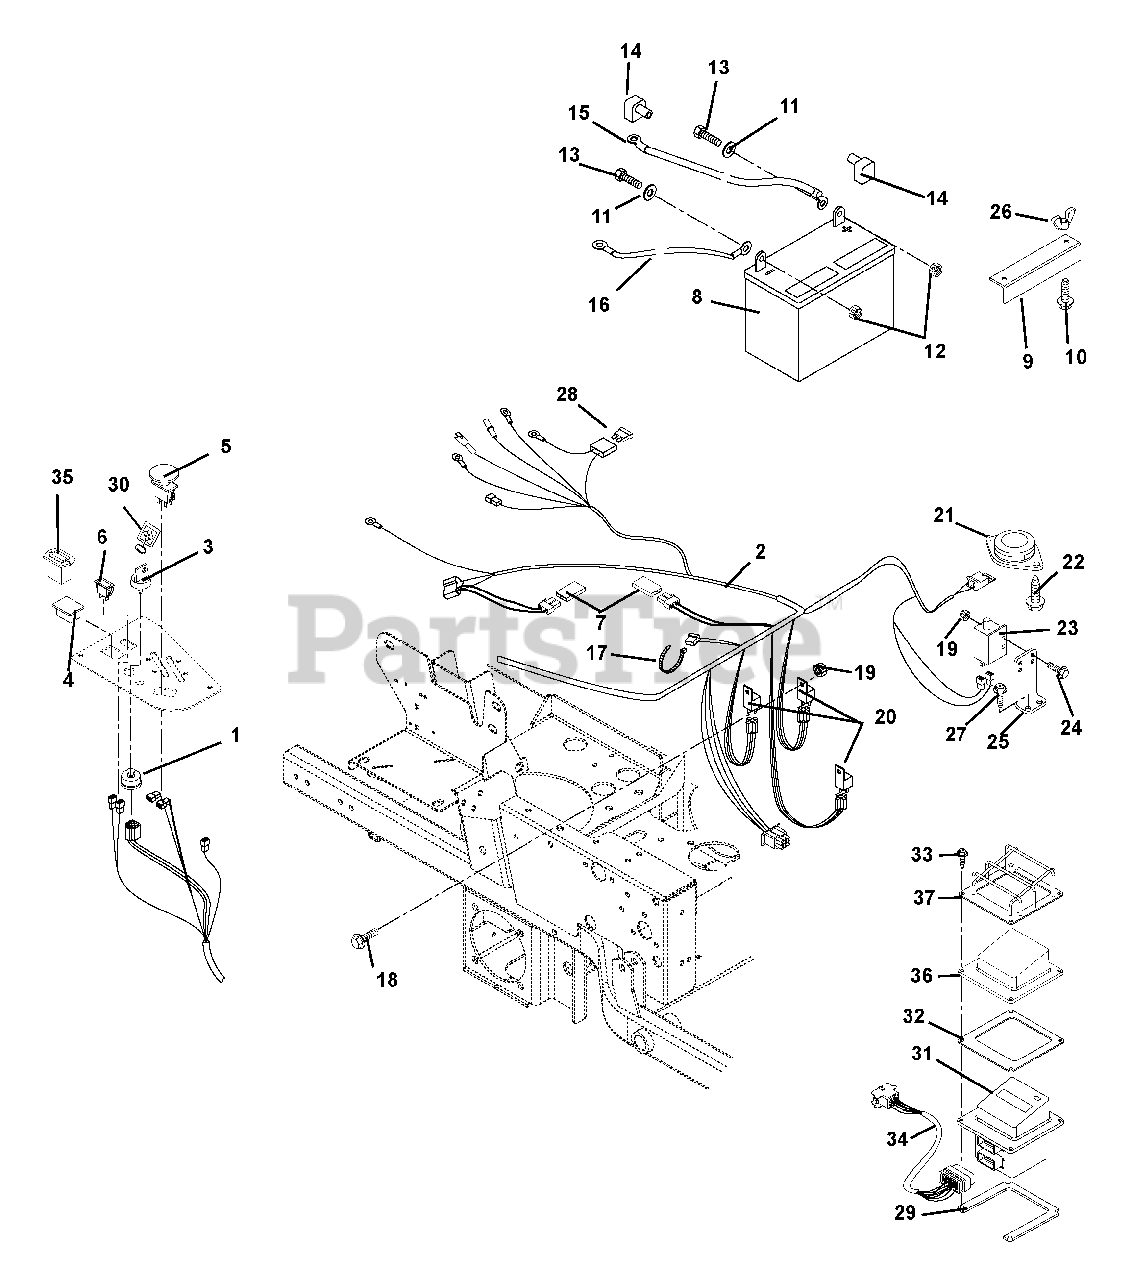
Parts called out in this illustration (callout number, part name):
1	Key Switch
2	Harness, IZ-6 Pin (EYE-Q)
3	Key with Shield
4	Plug (992077, 078, 079, 080, 081, 082, 310, 311)
5	Switch, Clutch With Retainer Ring
6	Light, Indicator
7	Diode, Connector Shell
9	Hold Down
10	Bolt, Round Head Square Neck .25-20 x 7.50
11	Washer, Flat Steel .281 x .620 x .065
12	Nut, Locking Top Flange .25-20
13	Bolt, Hex .25-20 x .75 Grade 5
14	Insulator
15	Cable, Positive, 26 inch
16	Cable, Negative Battery
17	Cable Tie
18	Screw, Machine 10-24 x .50 Hex Washer Head
19	Nut, Locking Nylon 10-24 With Insert
20	Relay
21	Seat Switch
22	Screw, Tapping 12-24 x .50 Hex Washer Head
23	Switch, Single Pole
24	Screw, Machine 10-24 x .75 Hex Washer Head
25	Mount, Brake Switch
26	Nut, Locking Wing .25-20
27	Screw, Tapping .25-20 x .50 Hex Washer Head
28	Fuse, 30 Amp
29	Spacer, Enclosure Mounting (Bottom) (992077, 078, 079, 080, 081, 082, 310, 311)
30	Key Chain
31	Assembly, Eye-Q (992077, 078, 079, 080, 081, 082, 310, 311)
32	Gasket, Eye-Q (992077, 078, 079, 080, 081, 082, 310, 311)
33	Screw, Machine 10-24 x 1.0 Slotted Pan Black (992077, 078, 079, 080, 081, 082, 310, 311)
34	Harness, Eye-Q (992077, 078, 079, 080, 081, 082, 310, 311)
35	Hour Meter (992042, 043, 044, 051, 054, 055)
36	Guard, Element Eye-Q (992077, 078, 079, 080, 081, 082, 310, 311)
37	Guard, Vinyl Eye-Q (992077, 078, 079, 080, 081, 082, 310, 311)
